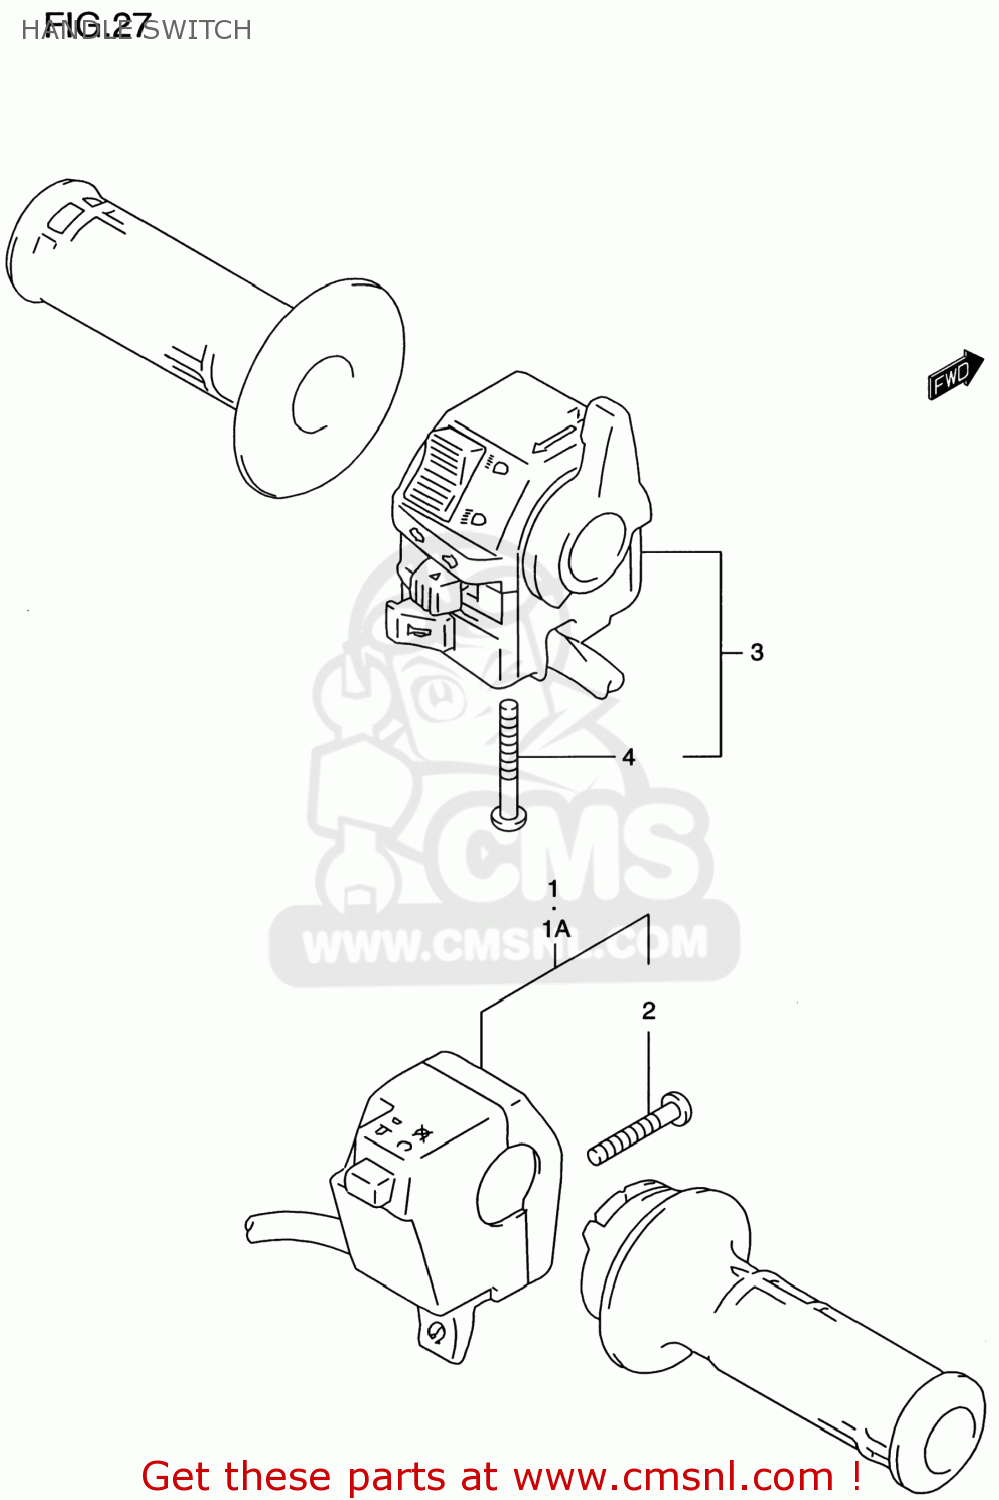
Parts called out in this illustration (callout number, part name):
1	SWITCH ASSY,HANDLE,R
1A	SWITCH ASSY,HANDLE,R
2	SCREW(5X25)
3	SWITCH ASSY,HANDLE,L
4	SCREW, 5X45
